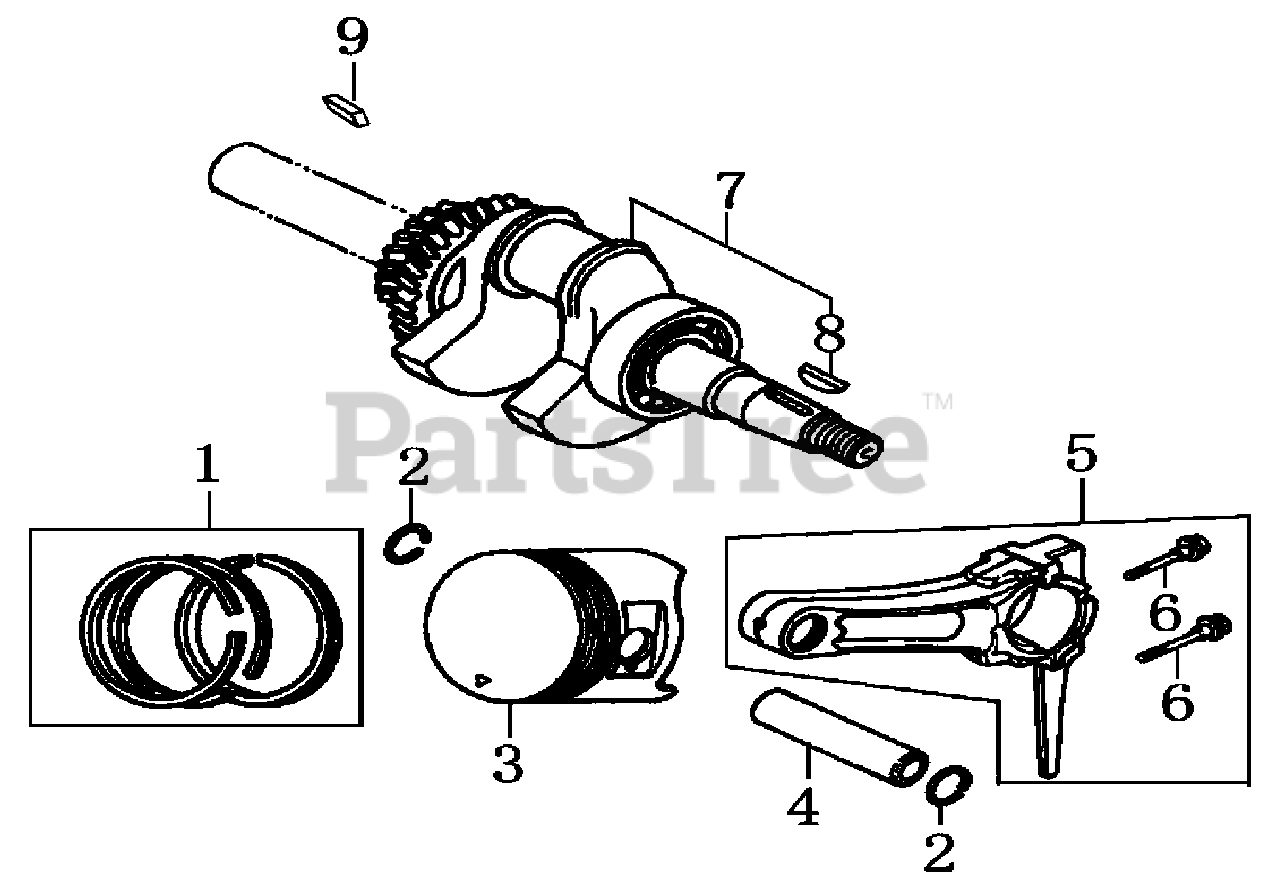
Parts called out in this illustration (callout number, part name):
1	RING SET, PISTON
2	CLIP, PISTON PIN
4	PIN, PISTON
5	ROD ASSY., CONNECTING
6	BOLT, CONNECTING ROD
7	CRANKSHAFT ASSY
8	KEY, SPECIAL WOODRUFF
9	KEY, CRANKSHAFT
